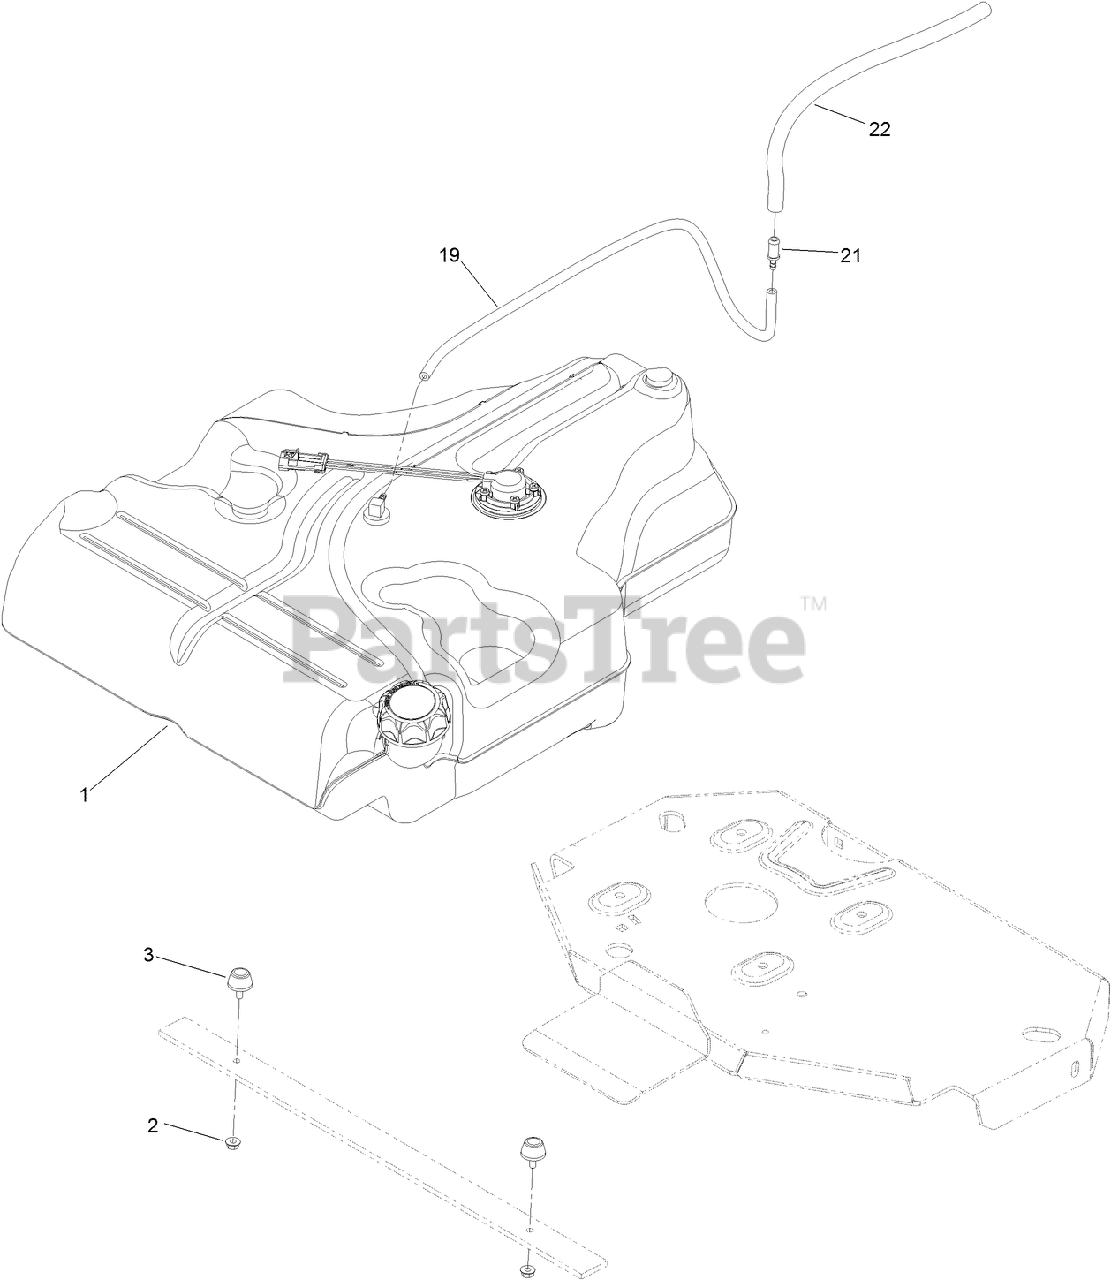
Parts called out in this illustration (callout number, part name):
1	FUEL TANK ASM
2	NUT-JAM
3	BUMPER-RUBBER (W/ STUD)
19	HOSE-FUEL
21	FITTING-STRAIGHT
22	HOSE-FUEL
